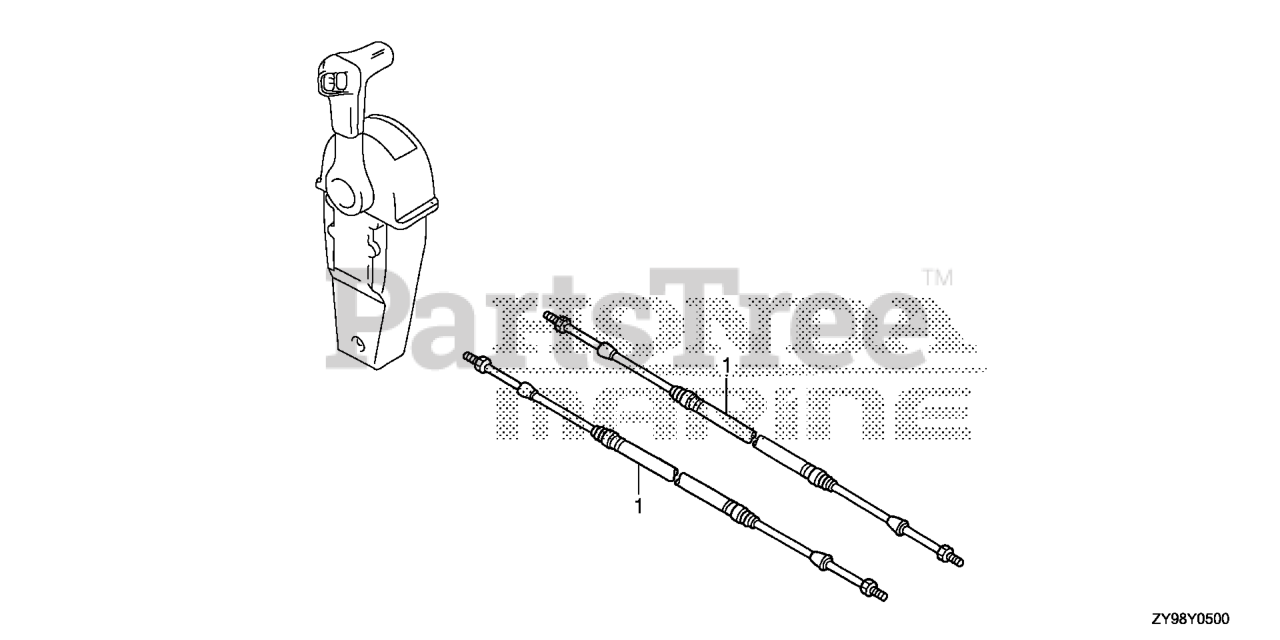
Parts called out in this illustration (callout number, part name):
1	CABLE, REMOTE CONTROL (5') (LOW FRICTION)
1	CABLE, REMOTE CONTROL (6') (LOW FRICTION)
1	CABLE, REMOTE CONTROL (7') (LOW FRICTION)
1	CABLE ASSY., PUSH-PULL (33HPC-7FT)
1	CABLE, REMOTE CONTROL (8') (LOW FRICTION)
1	CABLE, REMOTE CONTROL (9') (LOW FRICTION)
1	CABLE ASSY., PUSH-PULL (33HPC-9FT)
1	CABLE, REMOTE CONTROL (10'') (LOW FRICTION)
1	CABLE ASSY., PUSH-PULL (33HPC-10FT)
1	CABLE, REMOTE CONTROL (11'') (LOW FRICTION)
1	CABLE ASSY., PUSH-PULL (33C-6FT)
1	CABLE, REMOTE CONTROL (12'') (LOW FRICTION)
1	CABLE, REMOTE CONTROL (13'') (LOW FRICTION)
1	CABLE, REMOTE CONTROL (14'') (LOW FRICTION)
1	CABLE, REMOTE CONTROL (15'') (LOW FRICTION)
1	CABLE ASSY., PUSH-PULL (33C-10FT)
1	CABLE, REMOTE CONTROL (16'') (LOW FRICTION) (NOT AVAILABLE)
1	CABLE ASSY., PUSH-PULL (33C-11FT)
1	CABLE, REMOTE CONTROL (17'') (LOW FRICTION)
1	CABLE ASSY., PUSH-PULL (33HPC-17FT)
1	CABLE, REMOTE CONTROL (18') (LOW FRICTION) (NOT AVAILABLE)
1	CABLE ASSY., PUSH-PULL (33C-13 FT)
1	CABLE, REMOTE CONTROL (1 9'') (LOW FRICTION)
1	CABLE, REMOTE CONTROL (20'') (LOW FRICTION) (NOT AVAILABLE)
1	CABLE, REMOTE CONTROL (21') (LOW FRICTION)
1	CABLE, REMOTE CONTROL (22') (LOW FRICTION) (NOT AVAILABLE)
1	CABLE, REMOTE CONTROL (2 3'') (LOW FRICTION)
1	CABLE, REMOTE CONTROL (24') (LOW FRICTION) (NOT AVAILABLE)
1	CABLE, REMOTE CONTROL (25') (LOW FRICTION)
1	CABLE, REMOTE CONTROL (26') (LOW FRICTION)
1	CABLE ASSY., PUSH-PULL (33HPC-26FT)
1	CABLE ASSY., PUSH-PULL (33C-21FT)
1	CABLE, REMOTE CONTROL (27') (LOW FRICTION)
1	CABLE, REMOTE CONTROL (28') (LOW FRICTION) (NOT AVAILABLE)
1	CABLE ASSY., PUSH-PULL (33C-23FT)
1	CABLE, REMOTE CONTROL (2 9') (LOW FRICTION)
1	CABLE ASSY., PUSH-PULL (33C-24FT)
1	CABLE, REMOTE CONTROL (30') (LOW FRICTION) (NOT AVAILABLE)
1	CABLE, REMOTE CONTROL (31') (LOW FRICTION)
1	CABLE, REMOTE CONTROL (32') (LOW FRICTION) (NOT AVAILABLE)
1	CABLE ASSY., PUSH-PULL (33C-27FT)
1	CABLE, REMOTE CONTROL (33') (LOW FRICTION)
1	CABLE ASSY., PUSH-PULL (33C-28FT)
1	CABLE, REMOTE CONTROL (34') (LOW FRICTION)
1	CABLE ASSY., PUSH-PULL (33C-29FT)
1	CABLE, REMOTE CONTROL (35') (LOW FRICTION)
1	CABLE ASSY., PUSH-PULL (33C-32FT)
